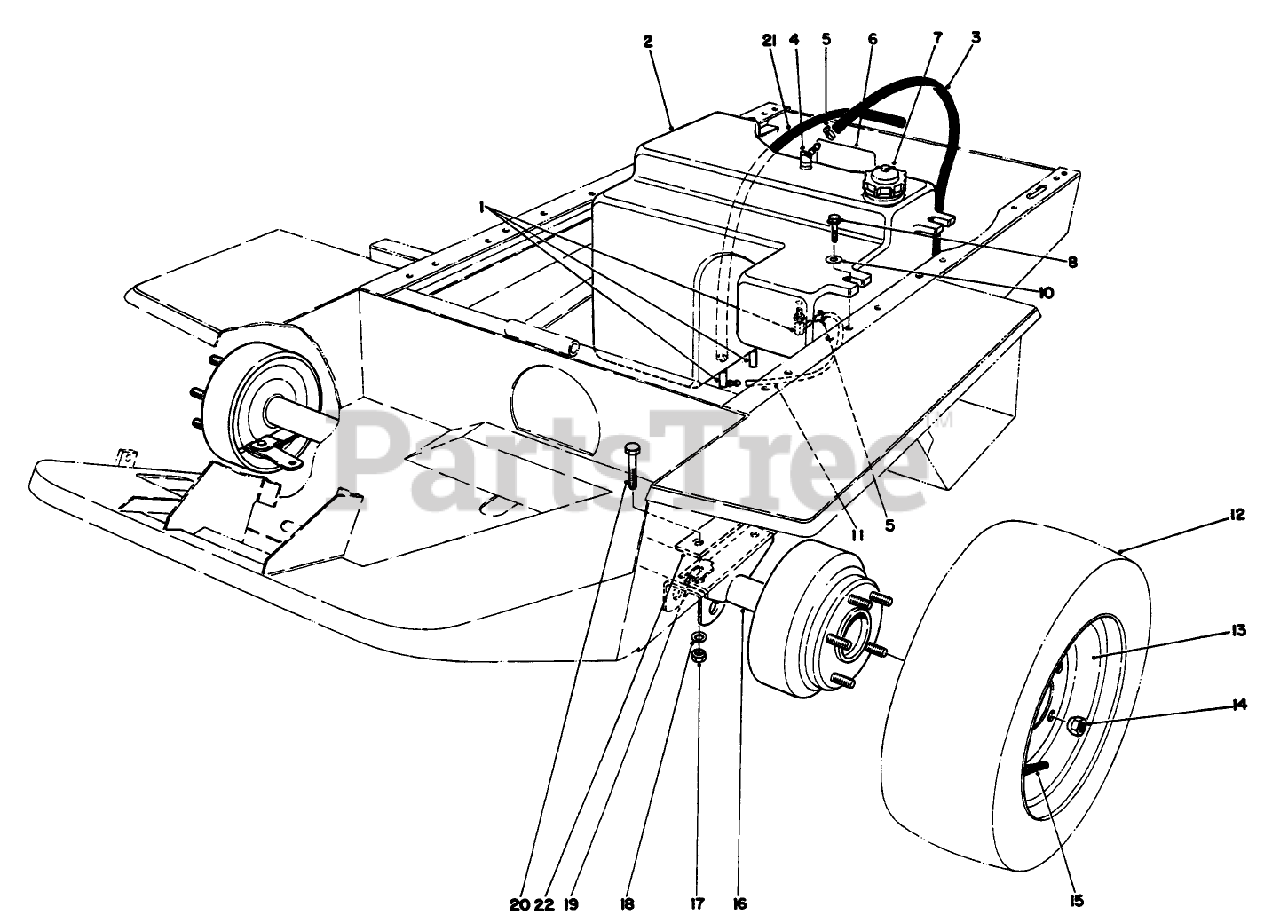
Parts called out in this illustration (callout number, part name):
1	FITTING-ELBOW, 90 DEG
2	Tank-Fuel (Incl. Ref. #1 & 3)
3	GAS TANK VENT HOSE
4	ELBOW
5	CLAMP-HOSE
6	DECAL-DANGER
7	GAS CAP ASSEMBLY
8	SCREW-HHF
10	WASHER
11	Hose-Fuel
12	20 X 8.00 - 10 TIRE
13	WHEEL ASM
14	NUT-WHEEL
15	VALVE STEM AND CAP ASM
16	Axle Assembly
17	NUT-HEX
18	WASHER-LOCK
19	SHIM-AXLE
20	SCREW-HH
21	HOSE
22	AXLE SPACER
